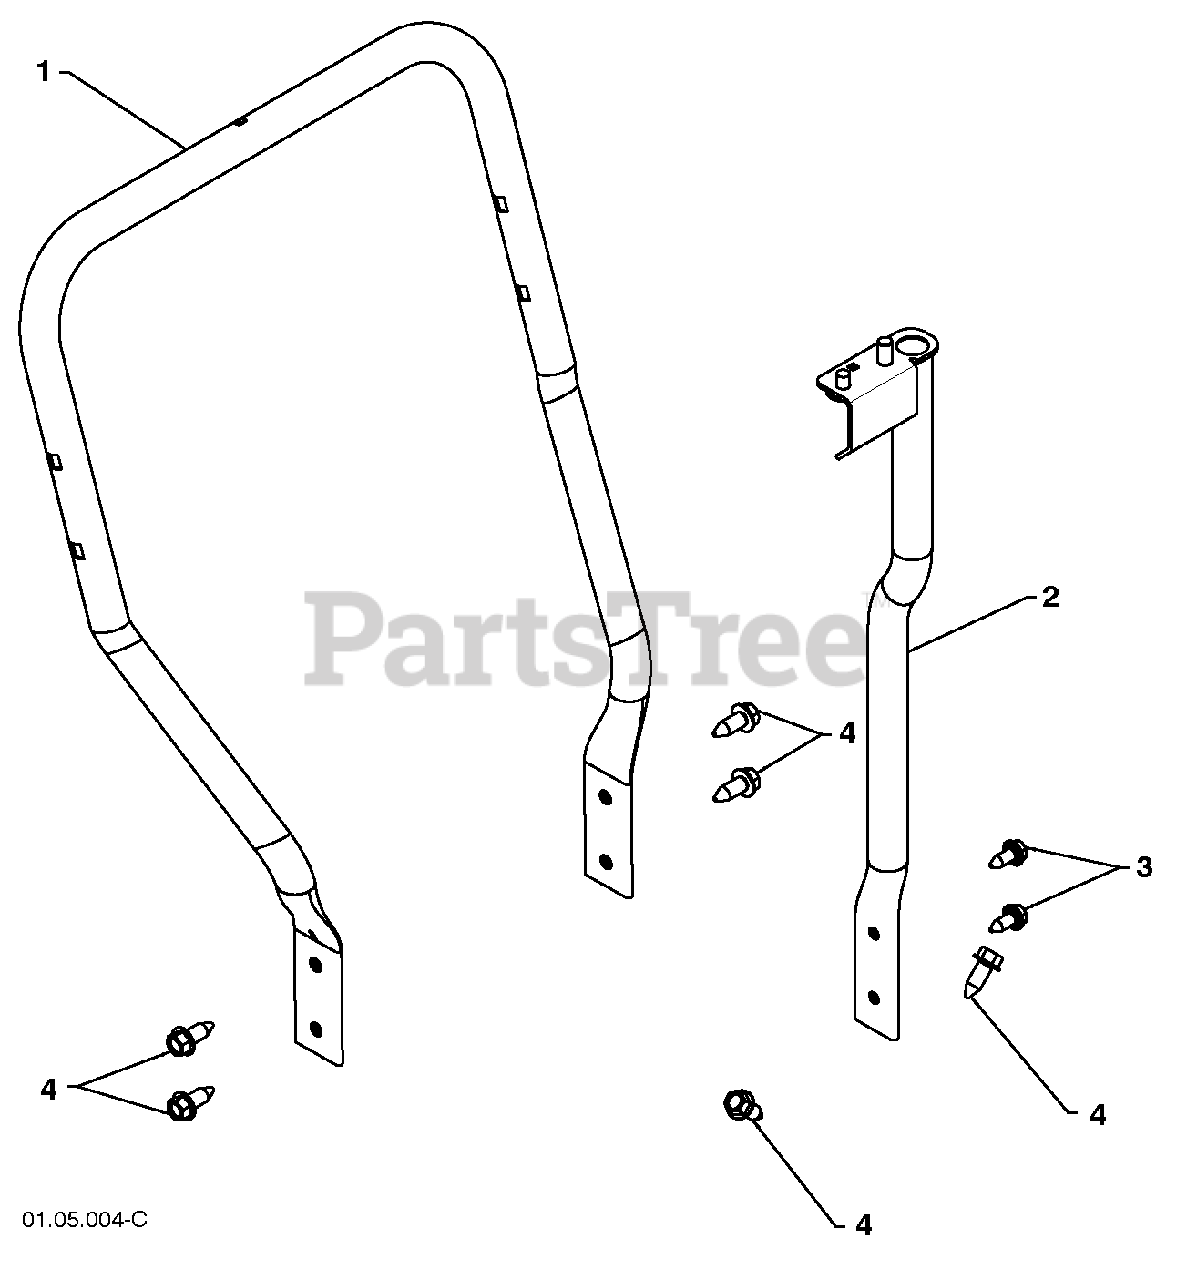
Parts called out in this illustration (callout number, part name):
1	LOWER TUBE
3	BOLT 5/16-18 X .750
4	SCREW 3/8-16 X 1.00
